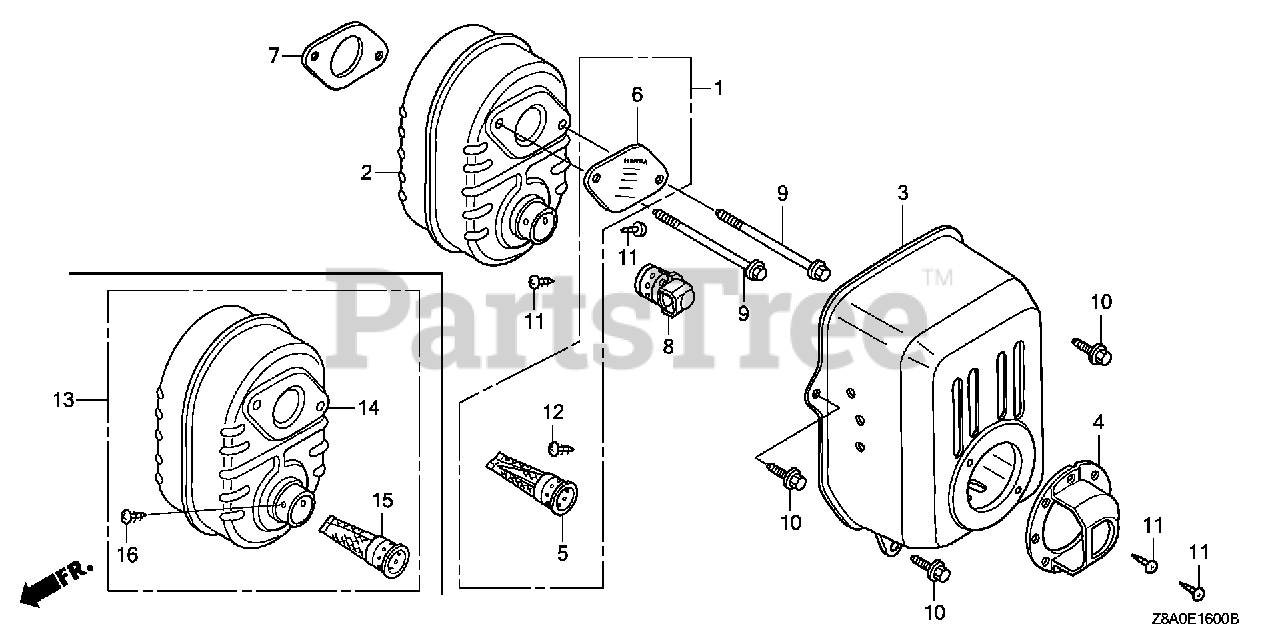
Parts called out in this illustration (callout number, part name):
1	ARRESTER KIT, SPARK
2	MUFFLER
3	PROTECTOR, MUFFLER
5	ARRESTER, SPARK (TO 1207644)
6	PLATE, ARRESTER NUMBER (TO INSTALL OPTIONAL SPARK ARRESTER)
7	GASKET, MUFFLER
9	BOLT, FLANGE (6X79) (CT200)
10	BOLT, FLANGE (6X12) (CT200)
12	SCREW, TAPPING (4X6) (TO INSTALL OPTIONAL SPARK ARRESTER)
13	MUFFLER ASSY. (ARRESTER)
14	MUFFLER
15	ARRESTER, SPARK
16	SCREW, TAPPING (4X6) (TO INSTALL OPTIONAL SPARK ARRESTER)
